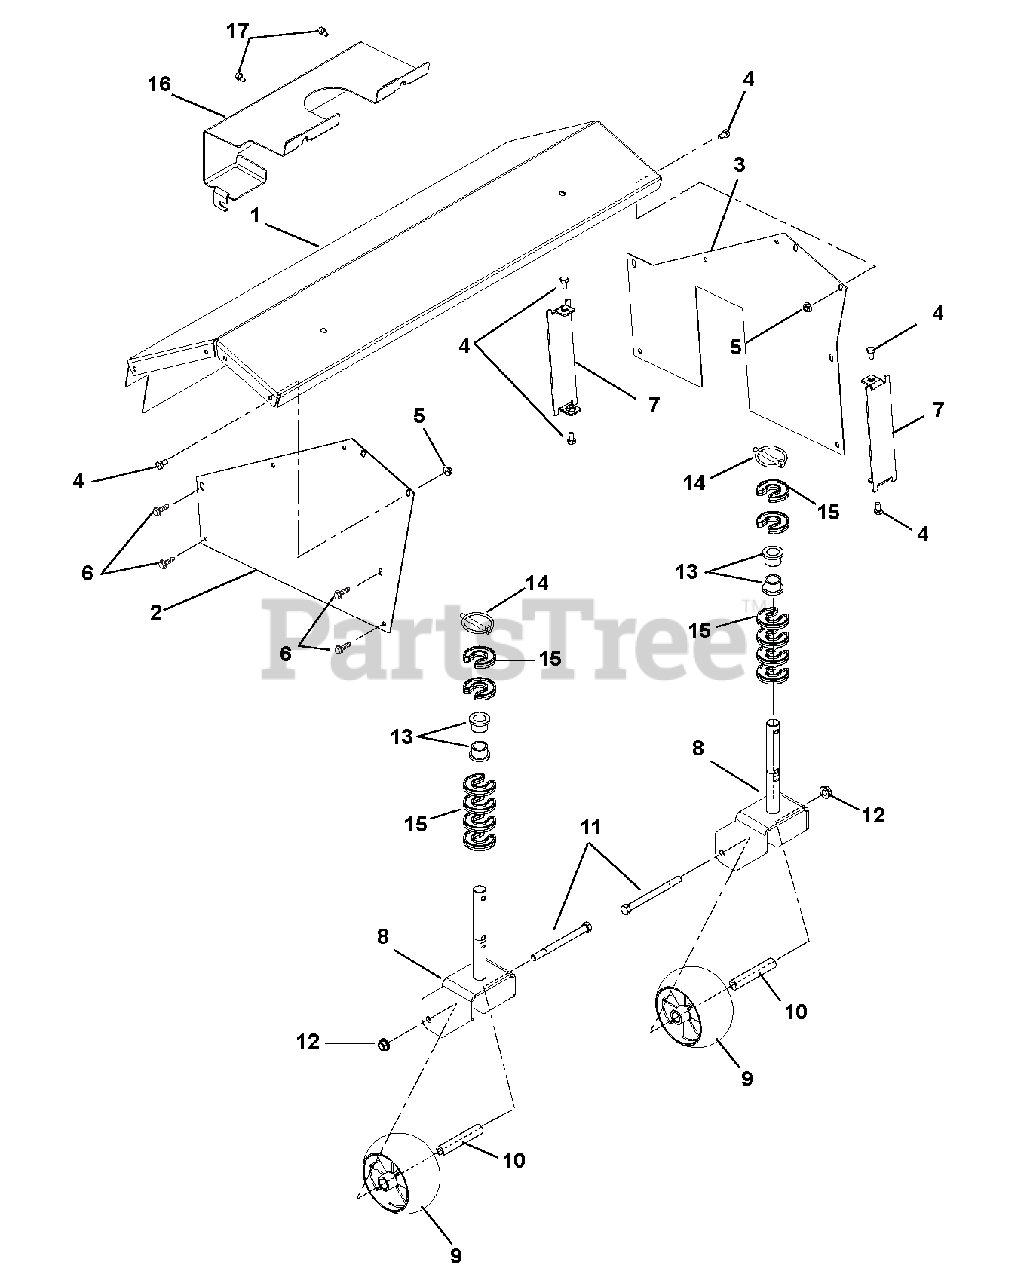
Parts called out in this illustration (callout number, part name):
1	COVER WITH DECALS, 28"BRUSH
2	COVER,RH SIDE BRUSH
3	COVER,LH SIDE BRUSH
4	@BLT-HEX .25-20X.50 GR5 YWZC
5	@NUT-LK-TOP-FLG .25-20 YWZC
6	SCR-TAP .25-20X.50 HWH TR YWZ
7	COVER,END
8	FORK, CASTER-BRUSH
9	ANTI-SCALP WHEEL - 5X3 CTR
10	SPACER, CASTER WHEEL
11	@BLT-HEX .38-16X4.50 GR5 YWZC
12	@NUT-LK-TOP-FLG .38-16 YWZC
13	BUSHING, FLANGE .75X.75X1.0
14	PIN, LYNCH - .25 X 1.25
15	CLIP-HOC FIXED
16	COVER, FRONT SHAFT - CE
17	SCR-TAP .25-20X.50 LGHWH TR YZ
